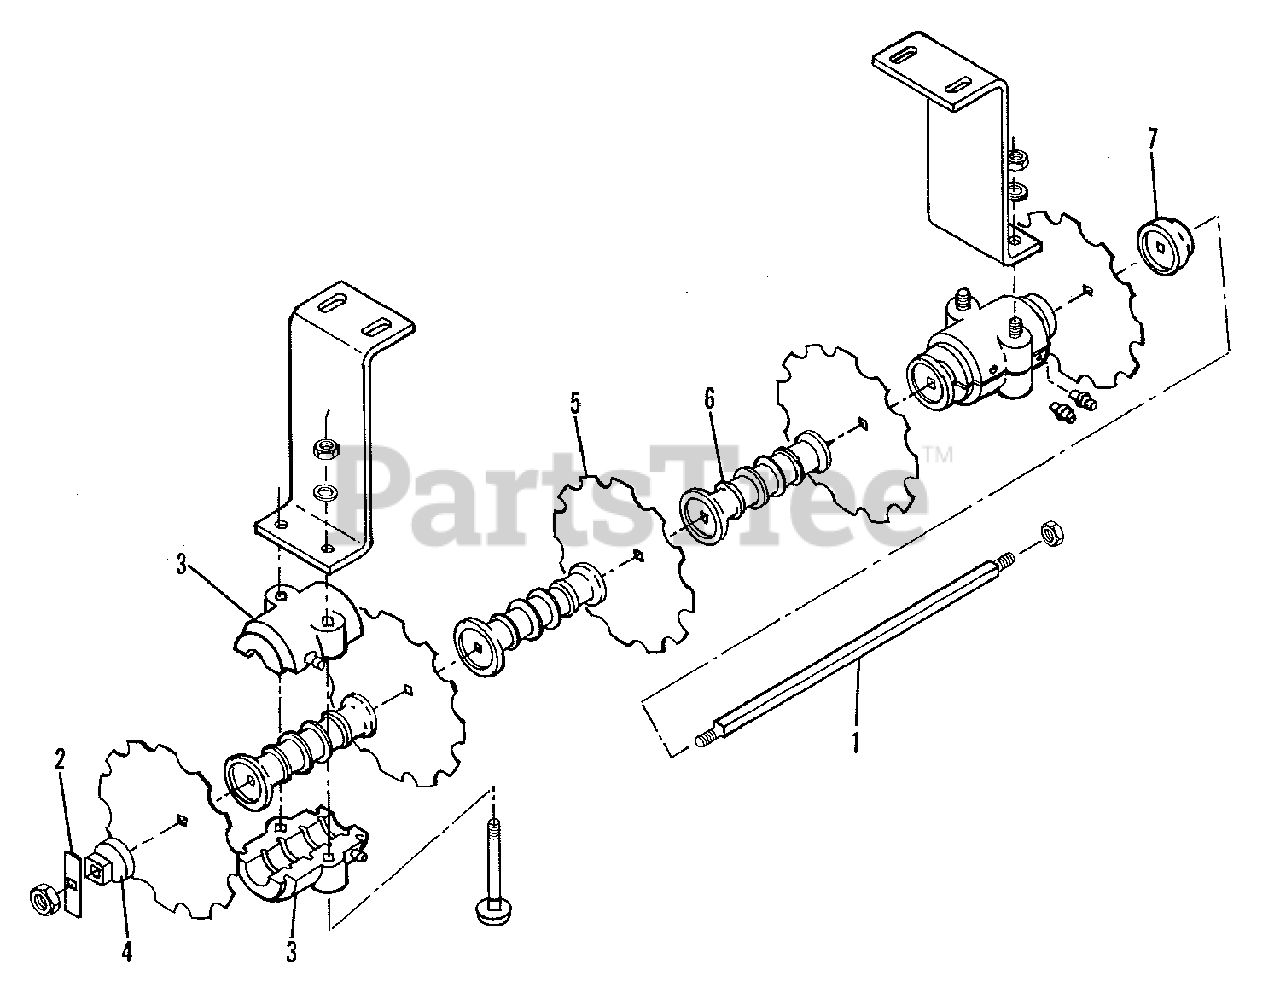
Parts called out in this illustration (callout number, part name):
1	AXLE, Gang, 33-1/2" Long (For 5 Blades)
1	AXLE, Gang, 26" Long (For 4 Blades)
2	PLATE, Lock
3	CAP, Bearing, Upper & Lower
3	BOLT, Carriage, 1/2NC x 5
3	LOCKWASHER, 1/2
4	WASHER, End
4	BLADE, Notched (18" Diameter)
4	BLADE, Notched (16" Diameter)
6	SPOOL, Bearing & Spacer
7	WASHER, Bumper
